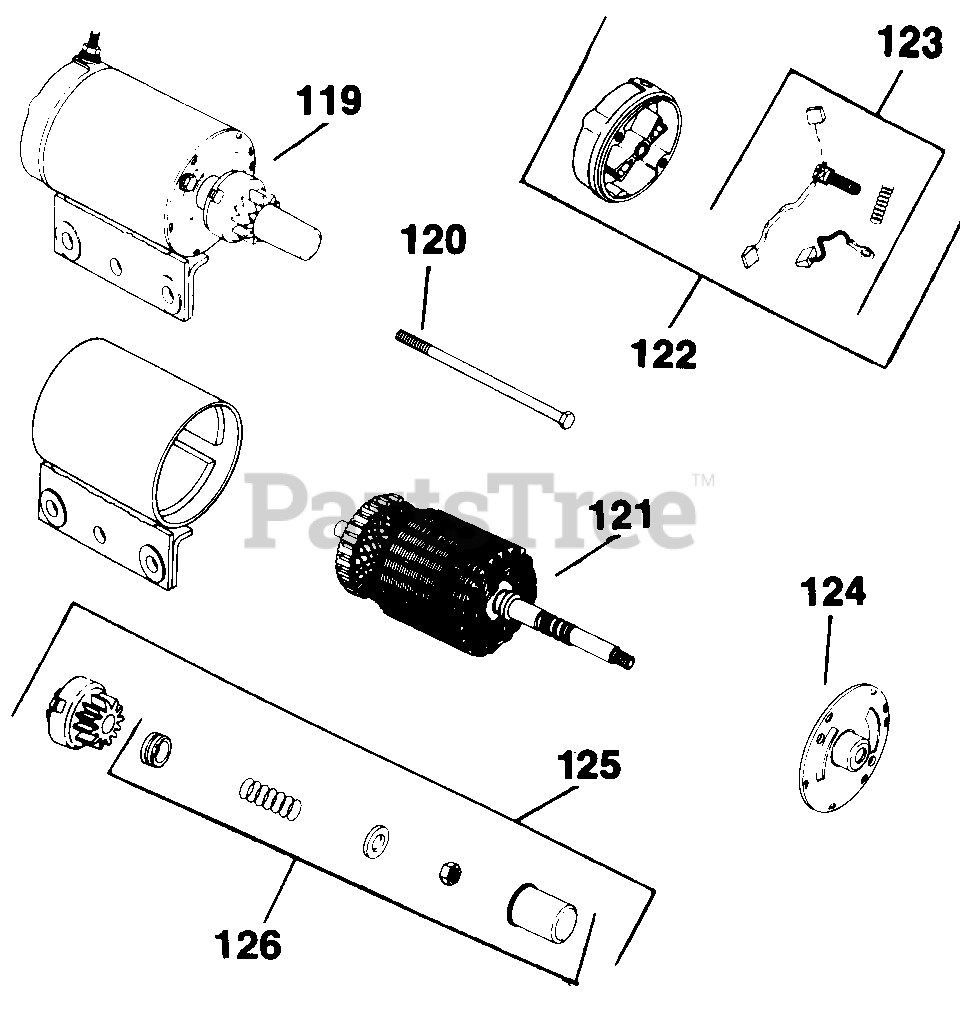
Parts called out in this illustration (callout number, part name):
119	STARTER - USE 45 098 07
121	ARMATURE - DISCONTINUED
122	CAP - DISCONTINUED
123	KIT - USE 52 755 15
124	CAP - USE 45 081 05
